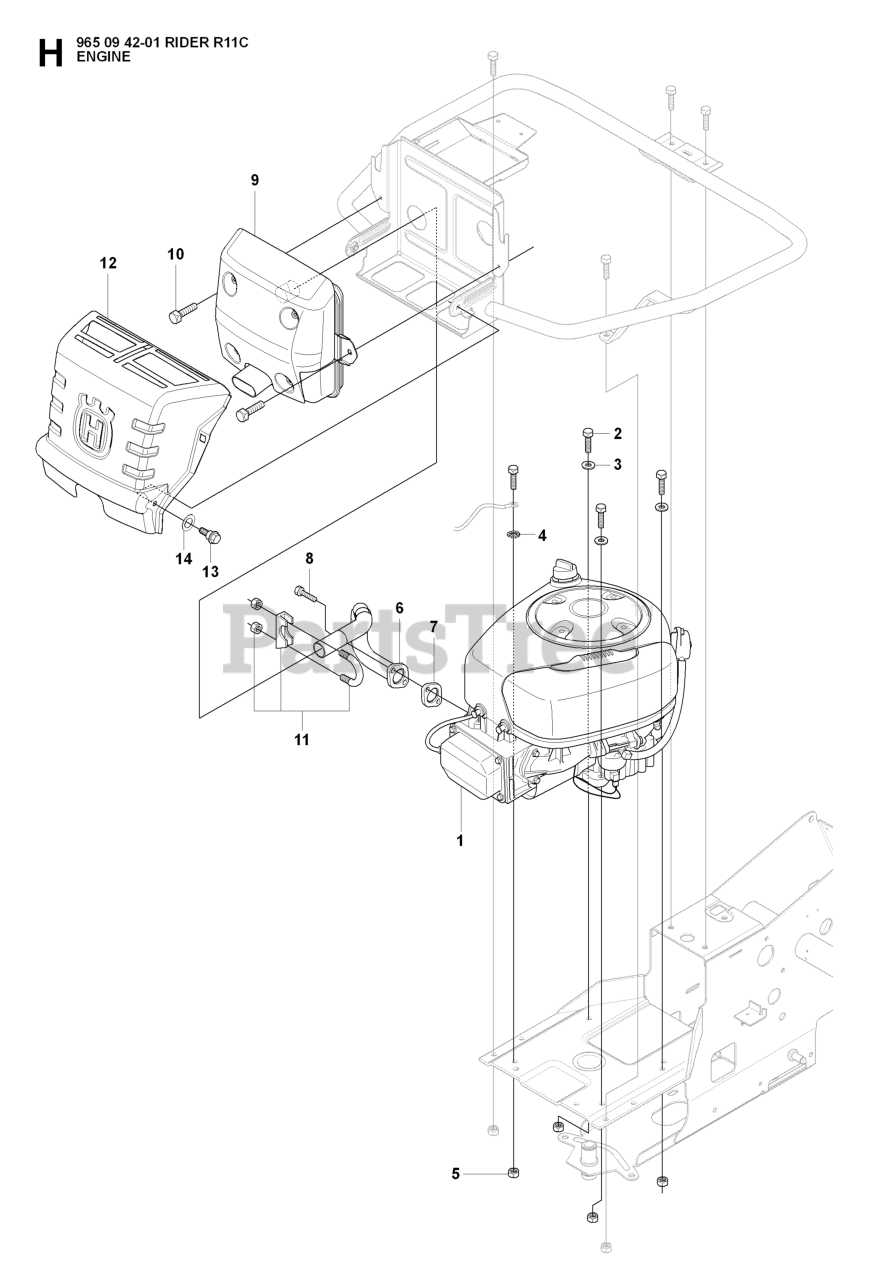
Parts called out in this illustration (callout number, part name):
3	WASHER BRB 8.4X17
5	LOCKNUT M8
6	EXHAUST PIPE ASSY
9	MUFFLER ASSY
11	CLAMP
12	HEAT PROTECTOR
14	SPRINGWASHER
